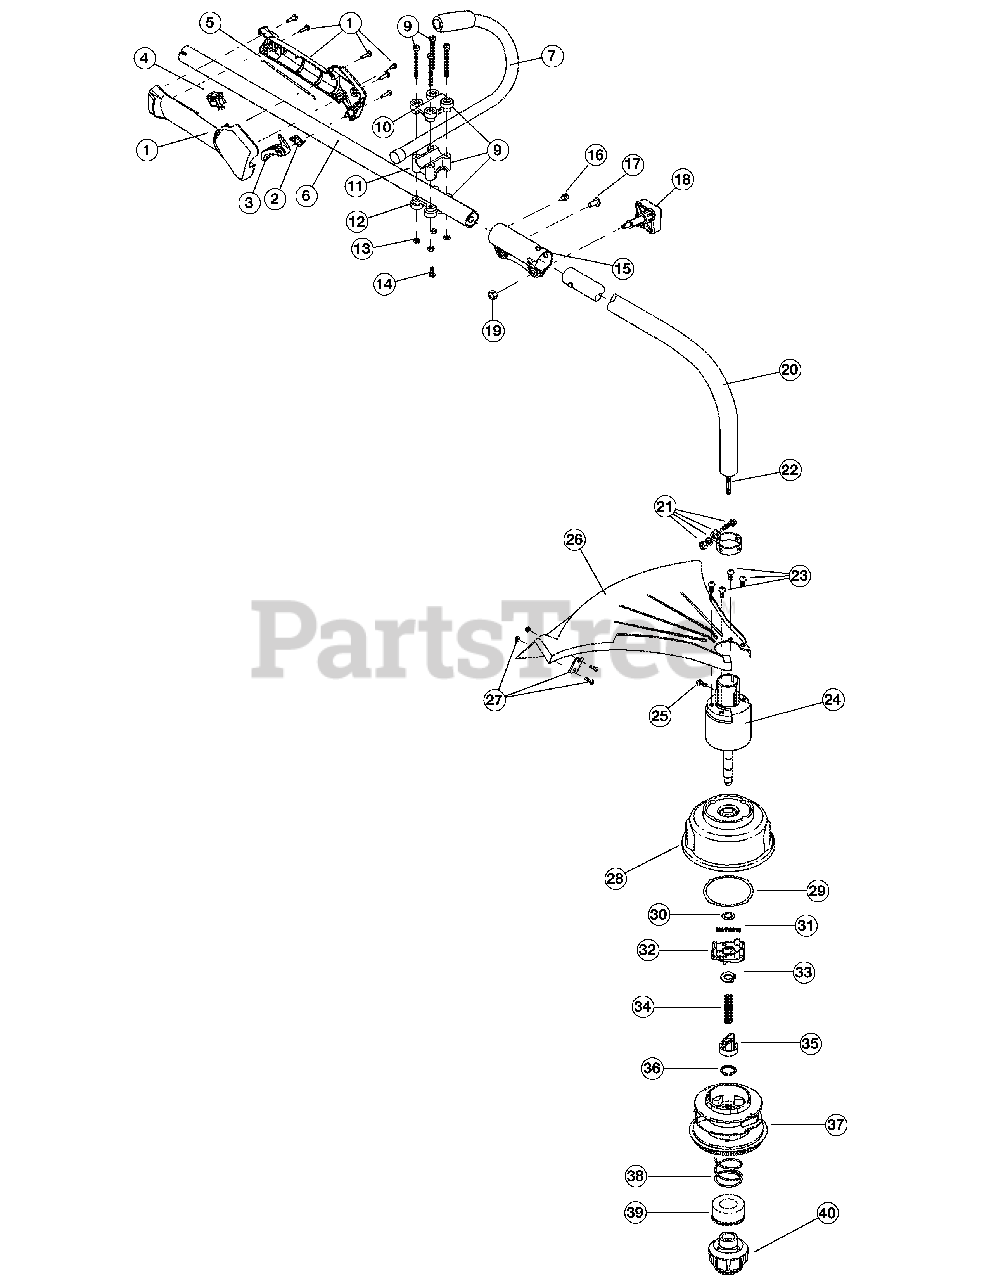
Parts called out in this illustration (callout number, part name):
1	Throttle Housing Assembly (includes 2-4)
2	Throttle Trigger Spring
3	Throttle Trigger
5	Throttle Cable Assembly
6	Upper Drive Shaft Housing Assembly
7	J-Handle Assembly
8	Handle Bracket Assembly (includes 9-14)
10	Upper Handle Clamp
11	Middle Handle Clamp
12	Lower Handle Clamp
14	Anti-Rotation Screw
15	Split boom Coupler (includes 12-15)
18	Adjustment Knob (includes 15)
19	Knob Retaining Nut
20	Lower Drive Shaft Housing Assembly
21	Lower Clamp Assembly (includes 21)
22	Lower Flexible Drive Shaft
23	Shield Mounting Screw
24	Bushing Housing Assembly
25	Anti-Rotation Screw
26	Shield Assembly (includes 23)
27	Blade Assembly
28	Outer Spool Assembly (includes 25)
30	Thrust Washer
31	Small Spring
37	Inner Reel
38	Large Spring
40	Bump Head Knob Assembly (includes 34 & 35)
